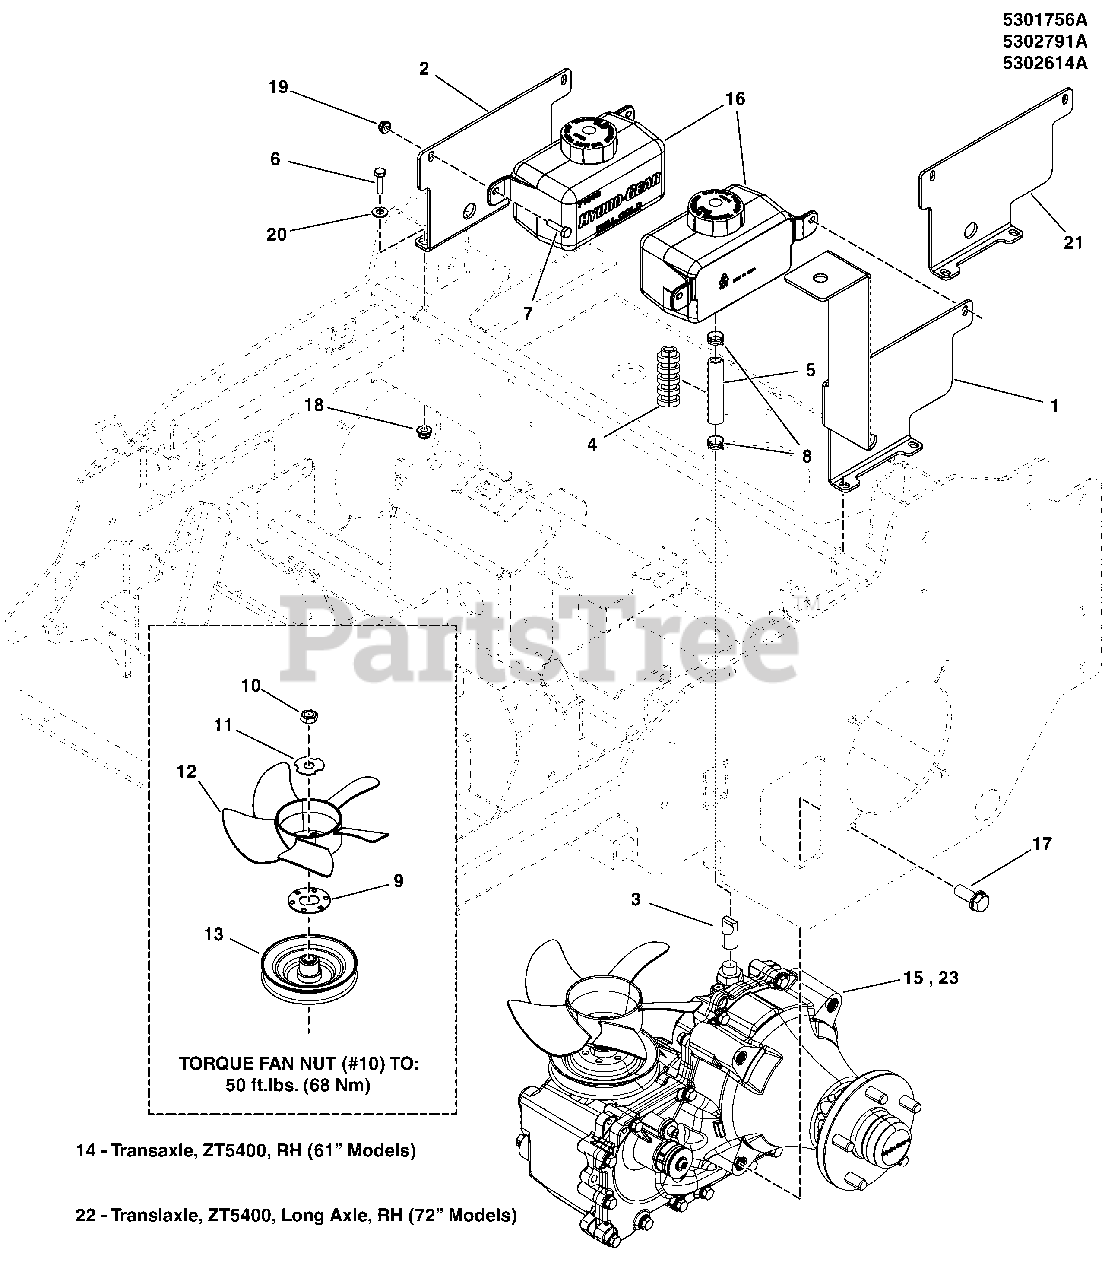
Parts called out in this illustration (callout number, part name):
1	PLATE, HYD BOT FUEL MNT LH, S200XT - BLK
2	PLATE, HYD BOT MOUNT, RH, S200XT - BLK
3	FITTING, BREATHER, ZT5400
4	LOOM, CONVOLUTED SPLIT, 1 ID - 7.00 LONG
5	HOSE, 5/8 PUSH LOCK, 9.00
6	BOLT, 5/16-18 X 3/4 GD5
7	BOLT, 1/4-20 X 1" GD5 CZ
8	CLAMP, #10 HOSE, STAINLESS
9	SPACER, ANTI ROTATE, ZT5400
10	NUT, ZT5400
11	WASHER, ZT5400, SLOTTED
12	FAN, ZT5400
13	PULLEY, ZT5400 (53177)
15	TRANSAXLE, ZT5400, LH, STANDARD AXLE (1015-1024)
16	HYDRO TANK, HYDRO-GEAR 71938, 1 LITER
17	BOLT, 1/2-13 X 1-1/4, SF, PLT W/PATCH
18	NUT, 5/16-18 HEX NYLOCK FLANGE
19	NUT, 1/4-20 HEX NYLOCK FLANGE
20	WASHER, 5/16" SAE
21	PLATE, HYD BOT MNT, SING TANK S200XT-BLK
23	TRANSAXLE, ZT5400, LH, LONG AXLE (1015-1057L)
